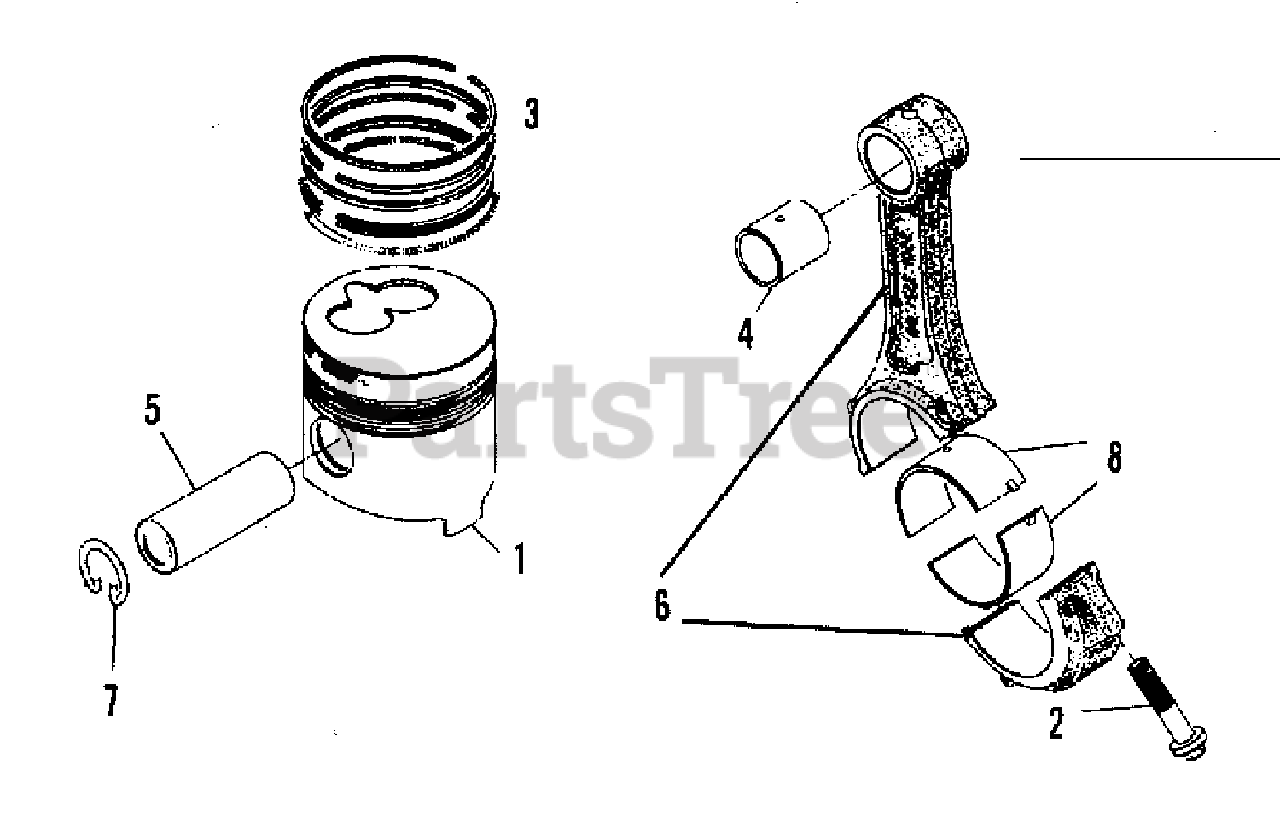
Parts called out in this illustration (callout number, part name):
1	PISTON, std.
1	PISTON, O.S.; 0.50
2	BOLT, connecting rod
3	RING SET, std.
3	RING SET, O.S.; 0.50
4	BUSHING, rod
5	PIN, piston
6	ROD ASSEMBLY, connecting (Incl. Item 2 & 4)
7	RING, piston retaining
8	BEARING, connecting rod, std.
8	BEARING, connecting rod, U.S.; 0.25
8	BEARING, connecting rod, U. S.; 0.50
